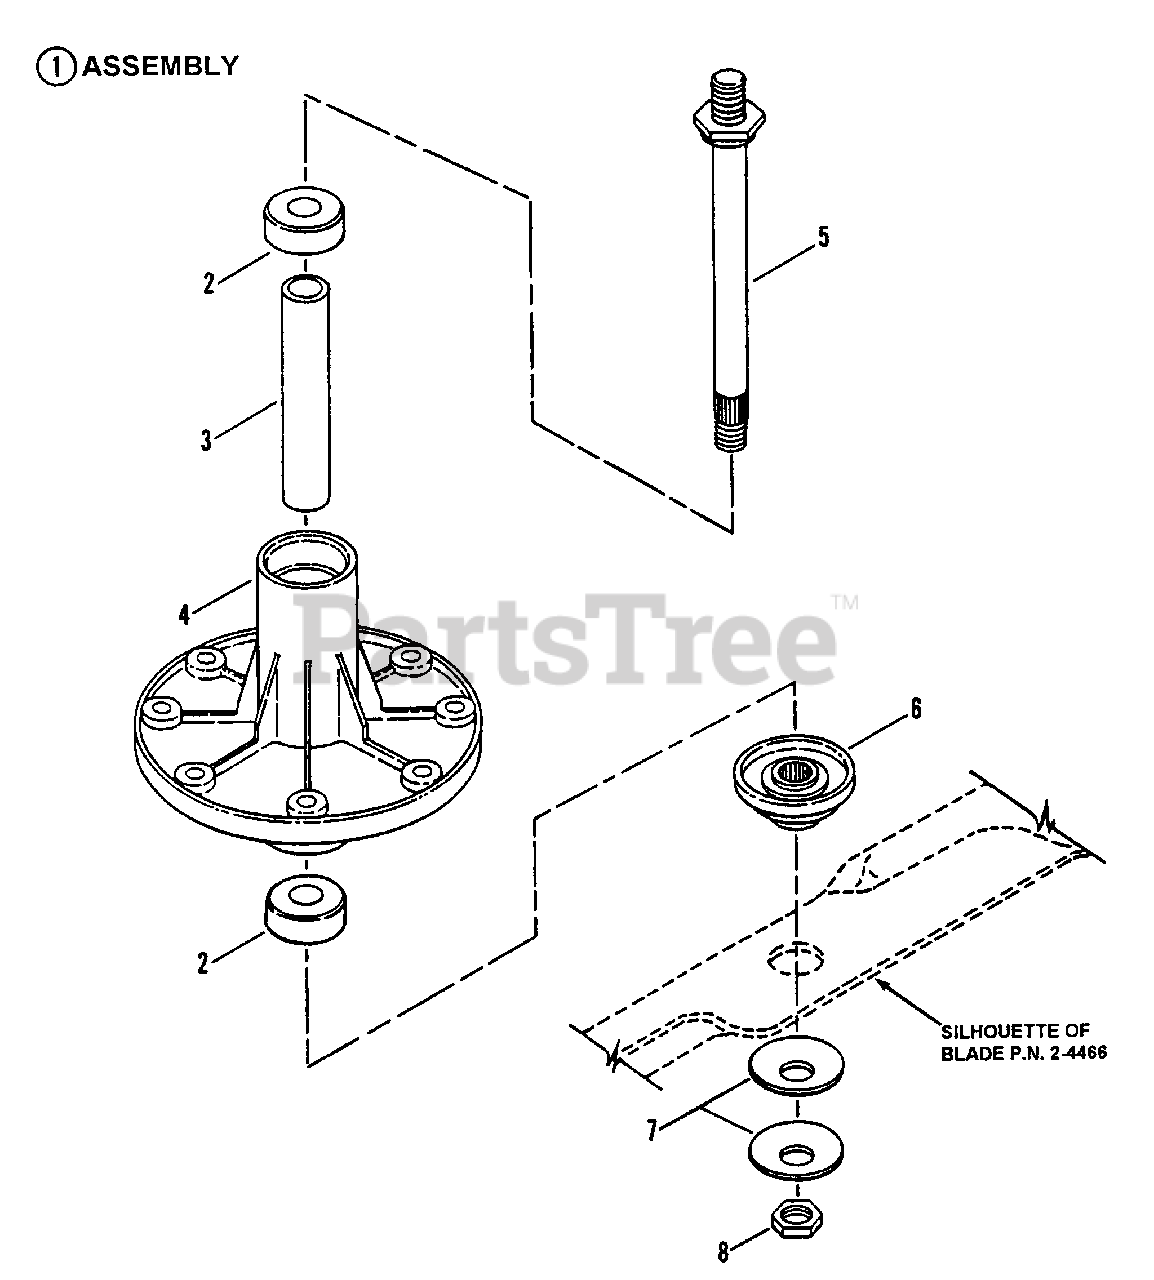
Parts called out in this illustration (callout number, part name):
1	ASSEMBLY, Spindle Housing, 38" Cutting Deck
2	BEARING, Spindle
3	SPACER, Spindle Housing
4	HOUSING, Spindle
5	SPINDLE, 7.019" Long
6	SPACER, Blade
7	WASHER, Belleville, 19/32" I.D. x 1 3/4" O.D.
8	NUT, 9/16-18 Hex Jam
